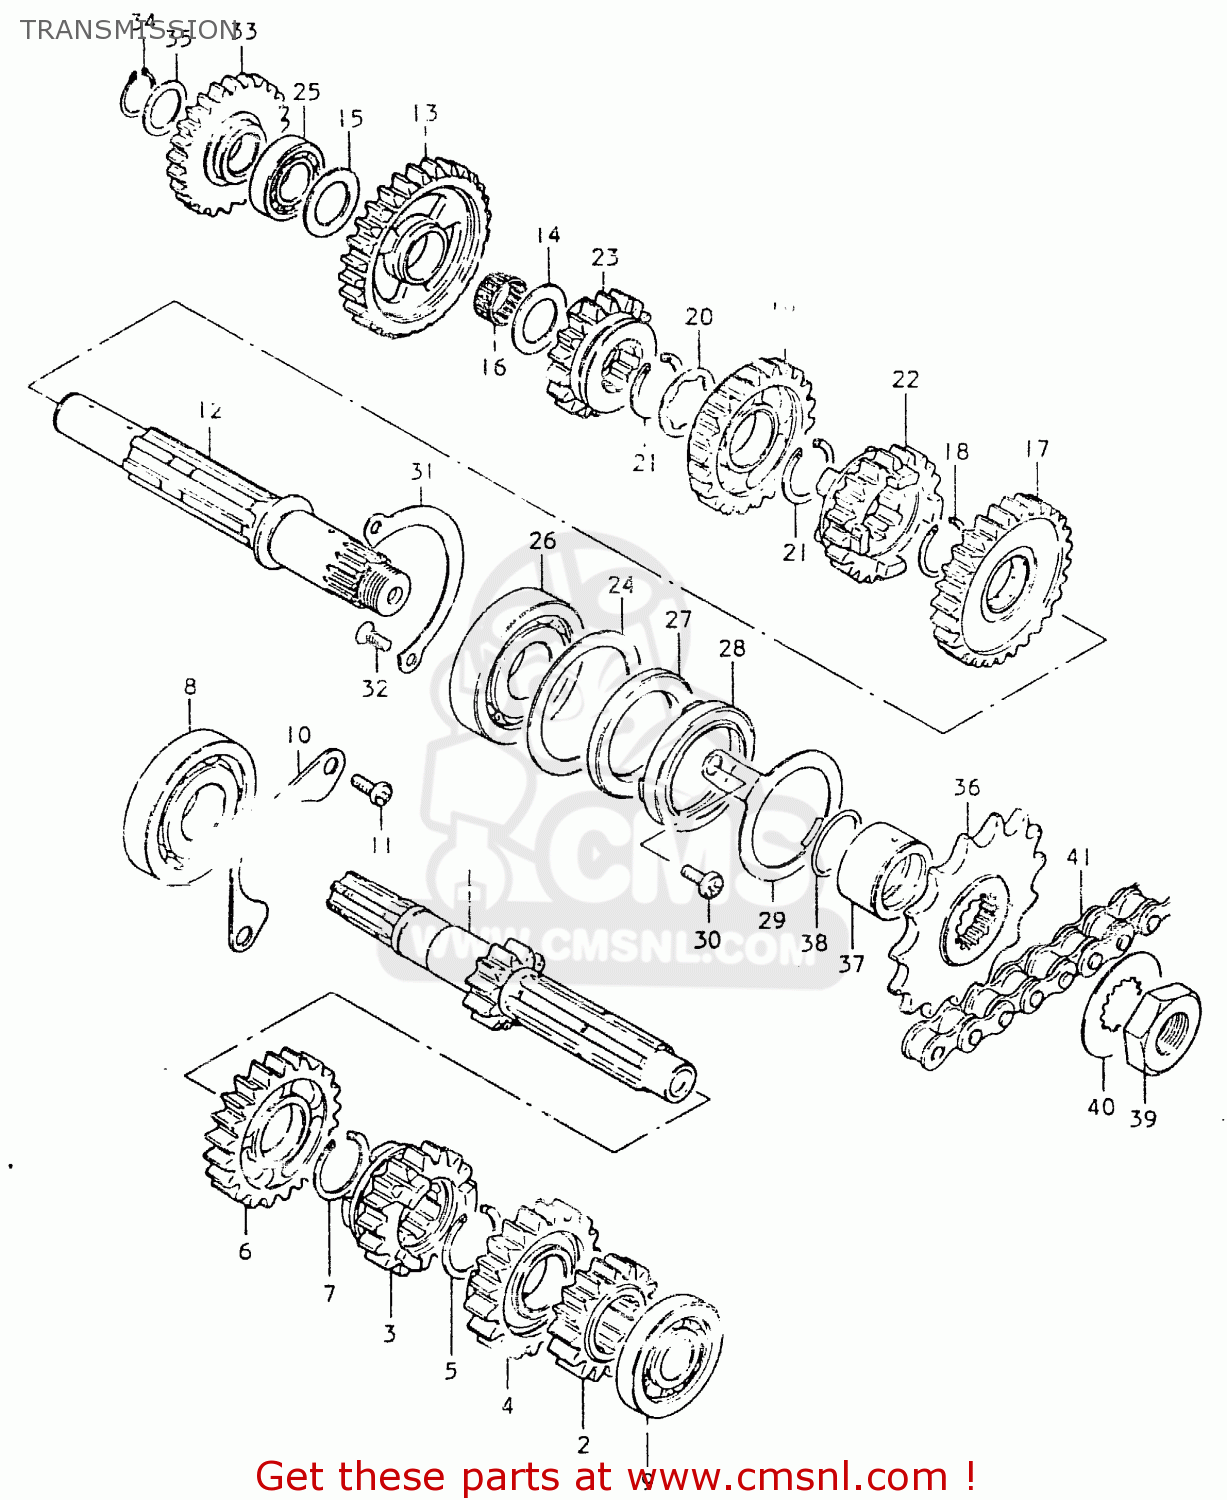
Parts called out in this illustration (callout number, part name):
1	SHAFT,COUNTER
2	GEAR,SECOND DRIVE
3	GEAR,THIRD DRIVE
4	GEAR,FOURTH DRIVE
5	CIRCLIP
6	GEAR,FIFTH DRIVE
7	CIRCLIP
8	BEARING
9	BEARING
10	PLATE,COUNTERSHAFT BEARING
11	SCREW 6X12
12	SHAFT,DRIVE
13	GEAR,FIRST DRIVEN
14	WASHER
15	WASHER
16	BEARING(17X21X9.8)
17	GEAR,SECOND DRIVEN
18	CIRCLIP
19	GEAR,THIRD DRIVEN
20	WASHER,LOCK
21	CIRCLIP
22	GEAR,FOURTH DRIVEN
23	GEAR,FIFTH DRIVEN
24	WASHER
25	BEARING(17X36X12)
26	BEARING(22X56X16)
27	OIL SEAL (30X47X5)
28	SEAL,OIL(30X47X7)
29	PLATE,DRIVESHAFT OIL
30	SCREW 6X12
31	RETAINER,DRIVE SHAFT BEARING
32	SCREW
33	GEAR,KICK STARTER IDLER(NT:25)
34	CIRCLIP
35	WASHER
36	SPROCKET,ENGINE(NT:15)
37	SPACER,ENGINE SPROCKET
38	O RING(D:2.5,ID:21)
39	NUT
40	WASHER,LOCK
41	CHAIN ASSEMBLY,DRIVE
